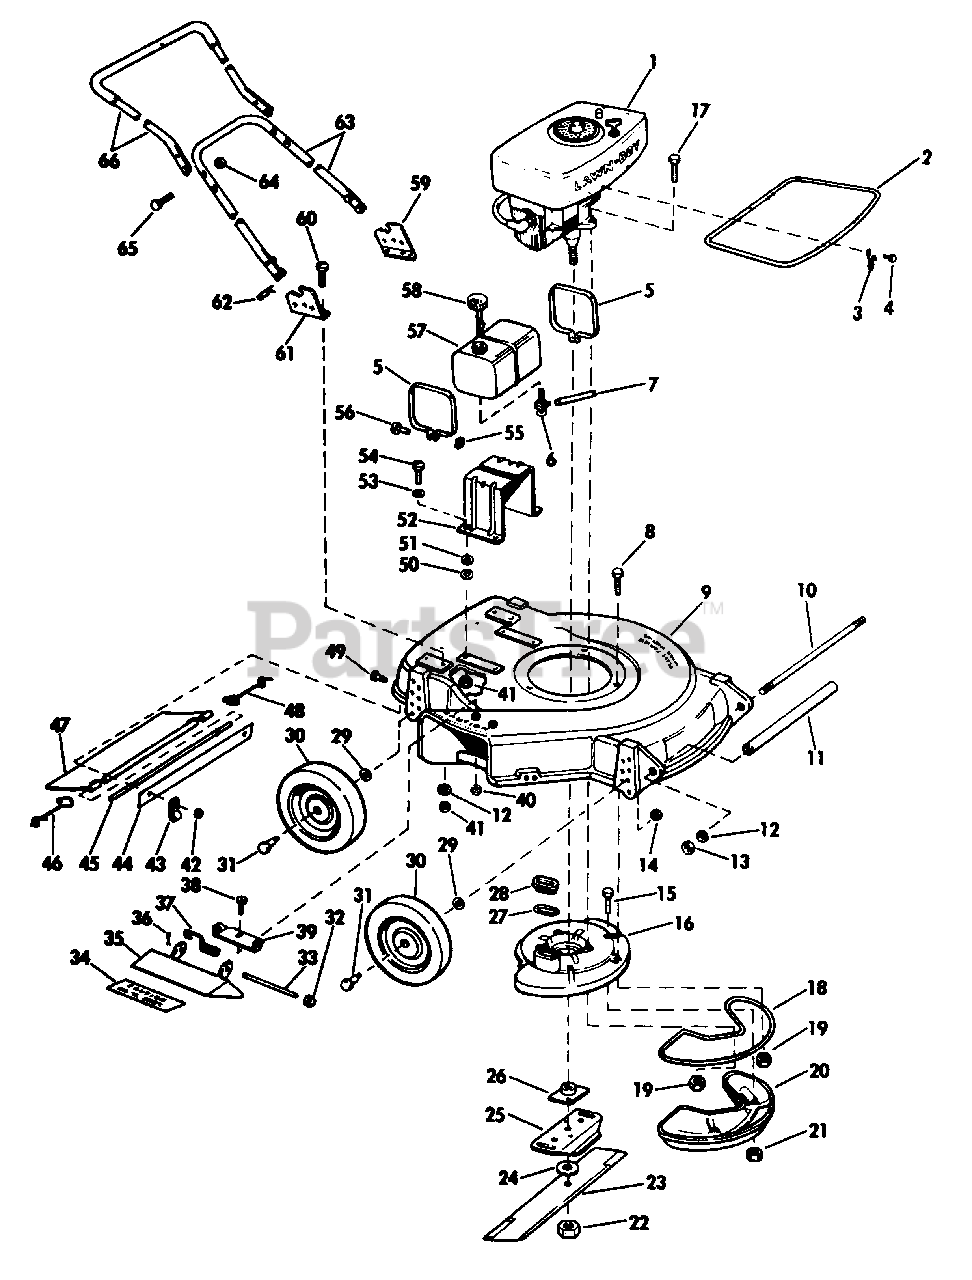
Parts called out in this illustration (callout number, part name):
1	See Page 38 for Engine, Magneto and Carburetor Parts List. See Note #2 at bottom of this page.
2	Loop-Arm. Plate Protective Wire
3	Spring-Wire Loop Mounting
4	Screw
5	Strap-Gas Tank
6	Shut-Off Valve & Screen
7	Gas Line
8	Screw-Muffler Plate to Housing
9	Housing & Bar Assembly-21"
10	Rod-Bumper
11	Bumper
12	Washer
13	Nut
14	Nut-Square
15	Screw
16	Muffler Plate Assembly
17	Screw
18	Gasket-Muffler
19	Nut-Nylok
20	Muffler
21	Nut
22	Blade Nut
23	Blade-21"
24	Washer-Blade
25	Stiffener-Blade
26	Collar & Plate
27	Gasket-Exhaust
28	Sleeve-Muffler Gasket
29	Lockwasher
30	Wheel & Tire Assy.-8"
31	Wheel Bolt-Shoulder
32	Push Nut
33	Pin
34	Decal
35	Deflector
36	Cotter Pin
37	Spring
38	Screw
39	Plate
40	Nut
41	Nut
42	Nut
43	Clamp
44	Extension
45	Bar
46	Spring-R.H.
47	Shield
48	Spring-L.H.
49	Screw
50	Washer
51	Grommet
52	Bracket-Gas Tank
53	Washer
54	Screw
55	Nut-Plain Square
56	Screw-Strap to Bracket
57	Gas Tank Assy.
58	Fuel Gauge Assy.
59	Handle Bracket, Left
60	Screw-Slotted
61	Handle Bracket, Right
62	Hair Pin
63	Handle Bottom & Pin Assy.
64	Nut Stop-Handle
65	Screw-Handle
66	Top Handle Section & Grip Assy.
